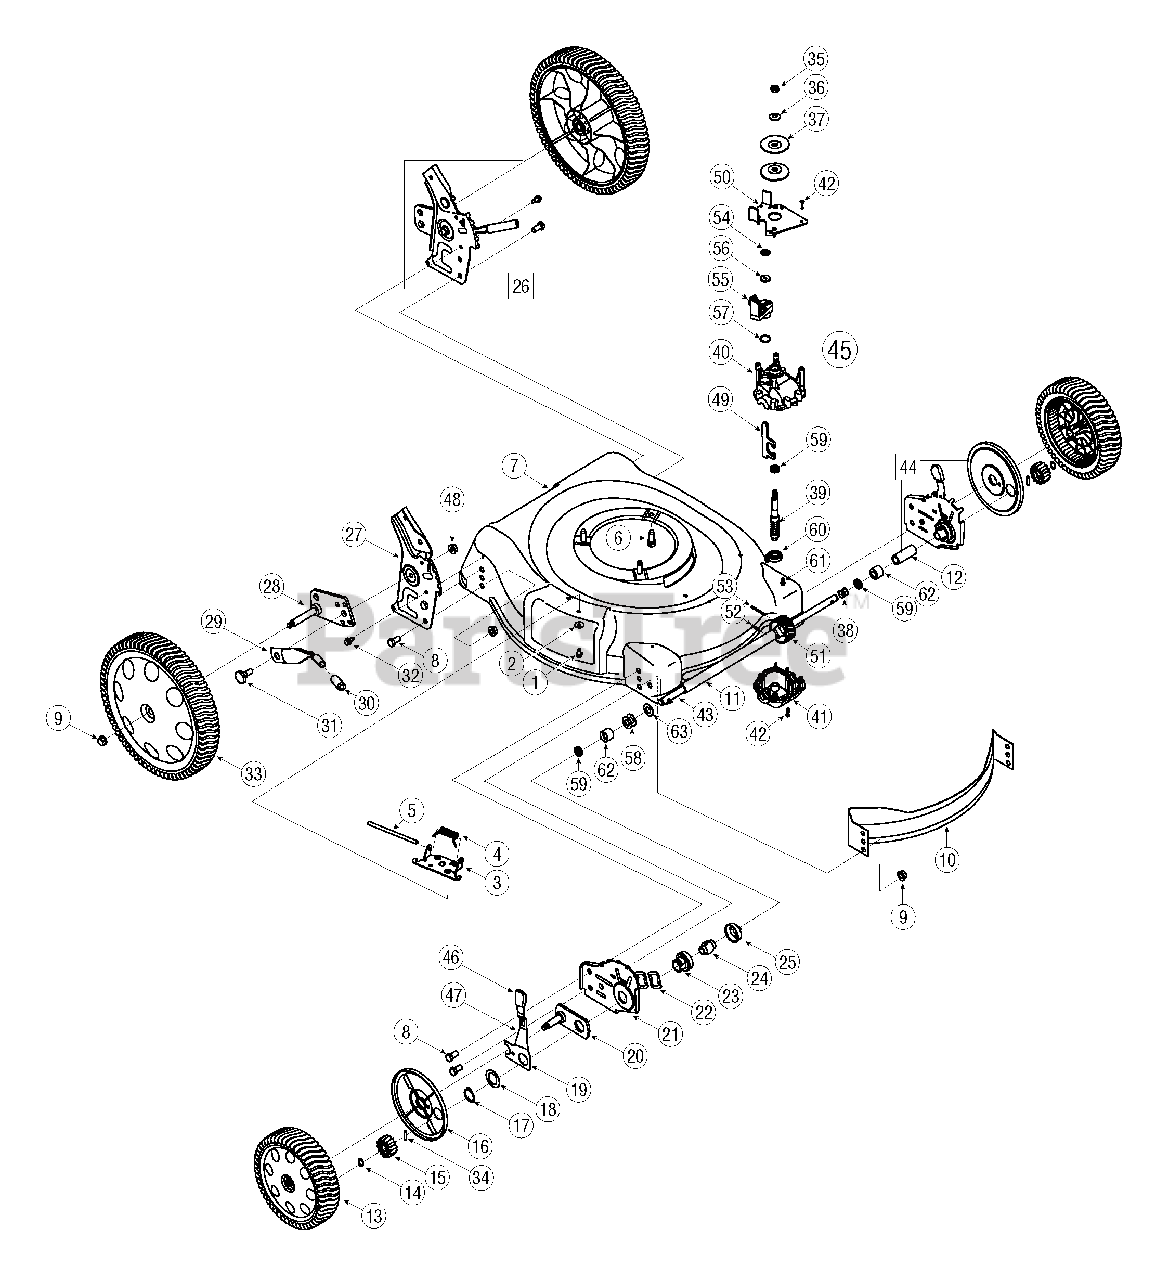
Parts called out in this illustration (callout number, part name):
1	TT Screw 1/4-20 x 0.5
2	Bell Washer.265 x 0.75
3	Deflector Chute Adapter
4	Torsion Spring
5	Hinge Pin
6	Self-Tapping Sems Screw
9	Hex Nut 3/8-16
10	Front Baffle
11	Sleeve Spacer 9.10" Lg.
12	Slev. Spacer 1.5" Lg.
13	Wheel 8 x 2.125 Gear
14	Snap Ring
15	Gear 14T RH FWD
16	Wheel Dust Cap
17	Snap Ring
19	Lever Assembly RH
20	Pivot Plate Assembly
23	Bearing Support
24	Bearing Sleeve
25	Bearing Retainer
26	Handle Bracket Assembly - LH
27	Handle Bracket - RH
28	Pivot Bar RH
29	Height Adjustment Lever
30	Foam Grip
31	Shoulder Scr.500 Dia. x.434
32	Tt Screw 1/4-20 x.625"
33	Wheel, 12 x 2.125
34	Dowel Pin
35	Hex Jam Nut 5/16-24
36	Bell Washer.325 x.930 x.45
37	Pulley, 3.82 x.313 x.68
38	Compression Spring
39	Pinion Shaft
40	Upper Housing
41	Lower Housing
42	Torx Screw
43	Output Shaft
44	Height Adjustment Assembly LH
45	Transmission Assembly Comp.
46	Adjustment Knob
47	Front Lever RH
48	Hex Flange Lock Nut 3/8-16
49	Shifter Fork
50	Transmission Bracket
51	28 Tooth Gear
52	Spirol Pin
53	Dowel Pin
54	Push Nut
55	Clutch Lever
56	Slotted Washer
57	O-ring
58	Flat Washer
59	Oil Seal
60	Ball Bearing
62	Plastic Bushing
63	Flat Washer
